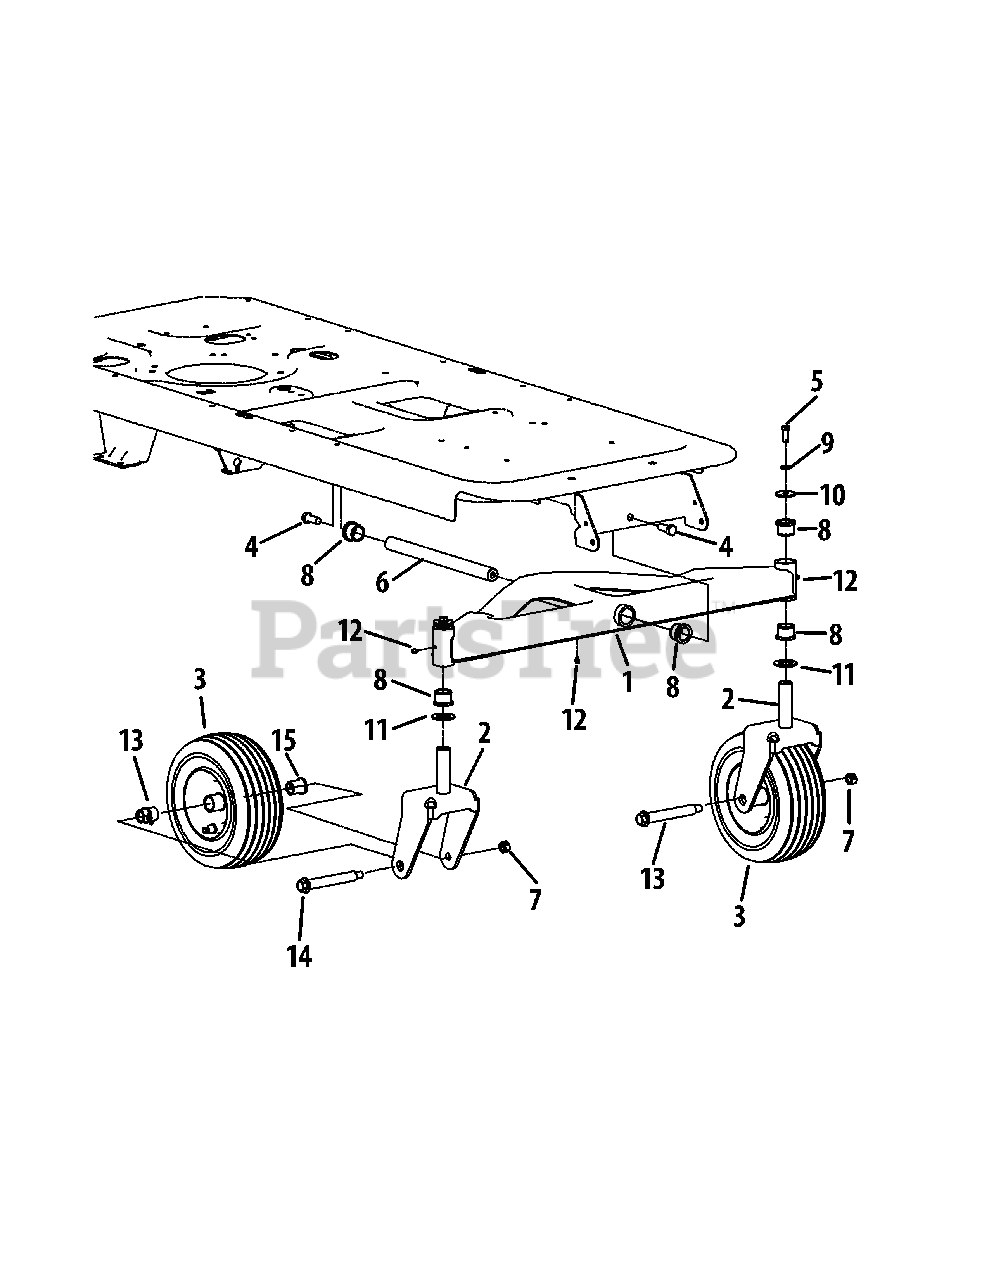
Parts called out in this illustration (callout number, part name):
1	Front Pivot Axle - Black
1	Front Pivot Axle - Red
2	Castor Wheel Bracket - Black
2	Castor Wheel Bracket - Red
3	Wheel Assembly, 11.0 x 4.0 x 5.0 Gray
4	Hex Lock Screw, 1/2-13 x 1.25
5	Hex Cap Screw, 3/8-16 x 1.0
6	Axle Shaft
7	Hex Lock Nut, 1/2-13
8	Flange Bearing, 1.0 x 1.246
9	Lock Washer, 3/8
10	Flat Washer, .39 x 1.5 x .134
11	Flat Washer, 1.0 x 1.75 x .107
12	Lube Fitting, 3/16 Drive
13	Shoulder Screw, .75 x 4.75 x 7/16-14
14	Flange Bearing, .76 x 1.0 x 1.2
15	Flange Bearing, .76 ID w/ Lube Ftg.
